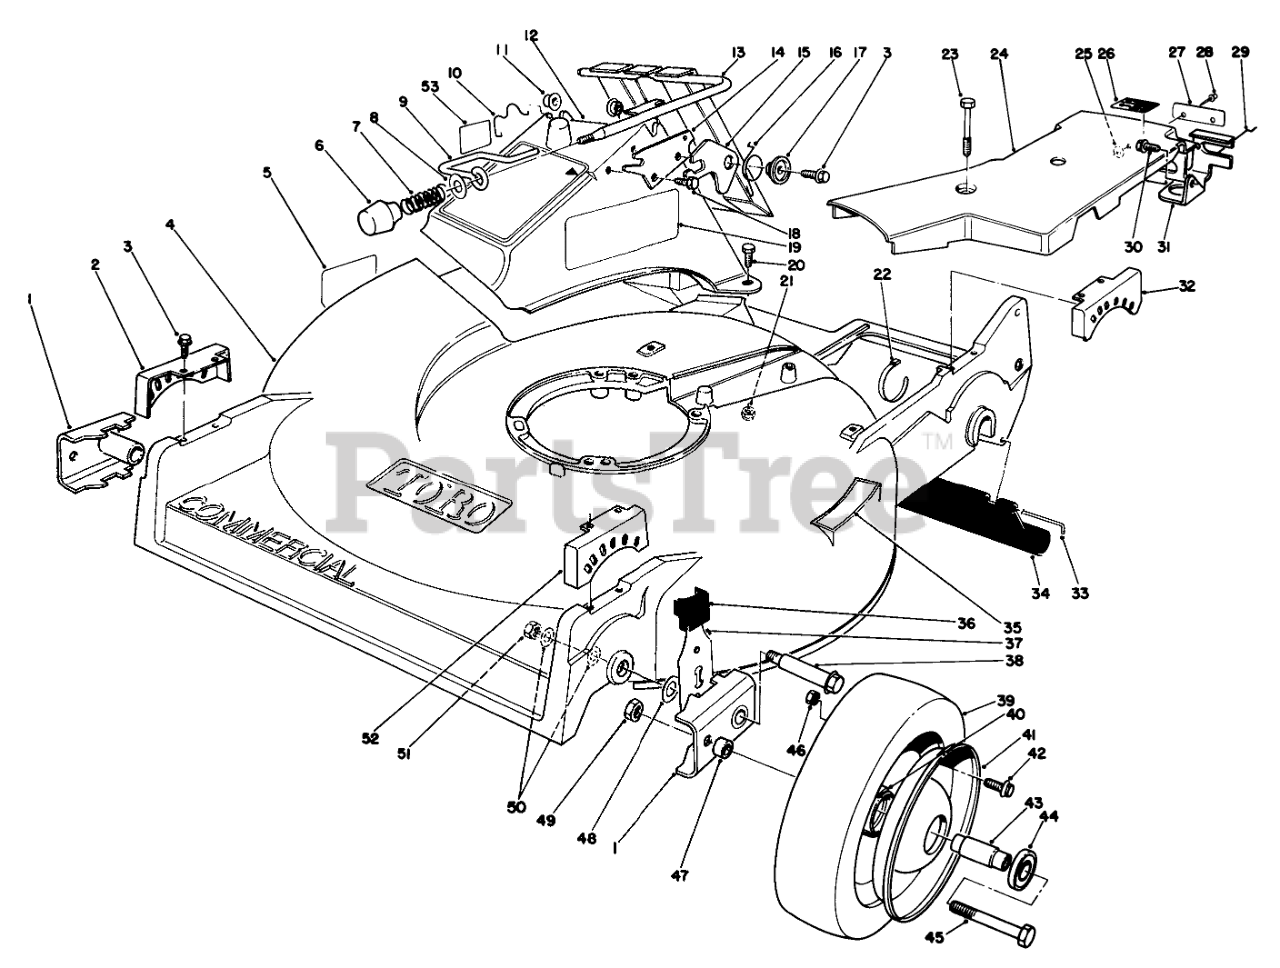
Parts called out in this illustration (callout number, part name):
1	ARM-PIVOT, FRONT
2	QUADRANT-FRONT, RH
3	SCREW-HWHTF
4	Housing-Commercial (Incl. Ref. #5 & 35)
5	Decal Danger
7	COMPRESSION SPRING
8	WASHER-FLAT
9	DOOR LATCH
10	DOOR RETAINER
11	BUSHING-NYLON
12	DISCHARGE CHUTE B
13	DOOR & HANDLE WA
14	DOOR LATCH PLATE
15	SAFETY LATCH
16	TORSION SPRING
17	DOOR SPACER
18	Screw
19	Decal-Danger
20	SCREW-HH
21	NUT-LOCK, NI
22	TIE-CABLE
23	SCREW-HHFTF
24	Belt Cover Assembly (Incl. Ref.#25, 27-28)
25	WASHER-PLAIN
26	Label-Grease
27	Name Plate-Ground Speed
29	RETAINER-CABLE
30	SCREW-HWHTF
31	Bracket-Traction Adj.
32	QUADRANT-REAR, LH
33	ROD-SHIELD
34	SHIELD-TRAILING
35	DECAL - STEP PAD INT'L
36	KNOB-ARM
37	Spring Arm Assembly Front
38	WHEEL BOLT
40	HUB-BEARING
41	Wheel-Half
42	SCREW-HHF
43	SPACER-BEARING
44	BEARING-WHEEL
45	SCREW-HH
46	NUT-LOCK, NI
47	SPACER-WHEEL
48	WASHER-THRUST
49	NUT-LOCK, CONE
50	WASHER
51	Nut
52	QUADRANT-FRONT, LH
53	DECAL - DANGER
